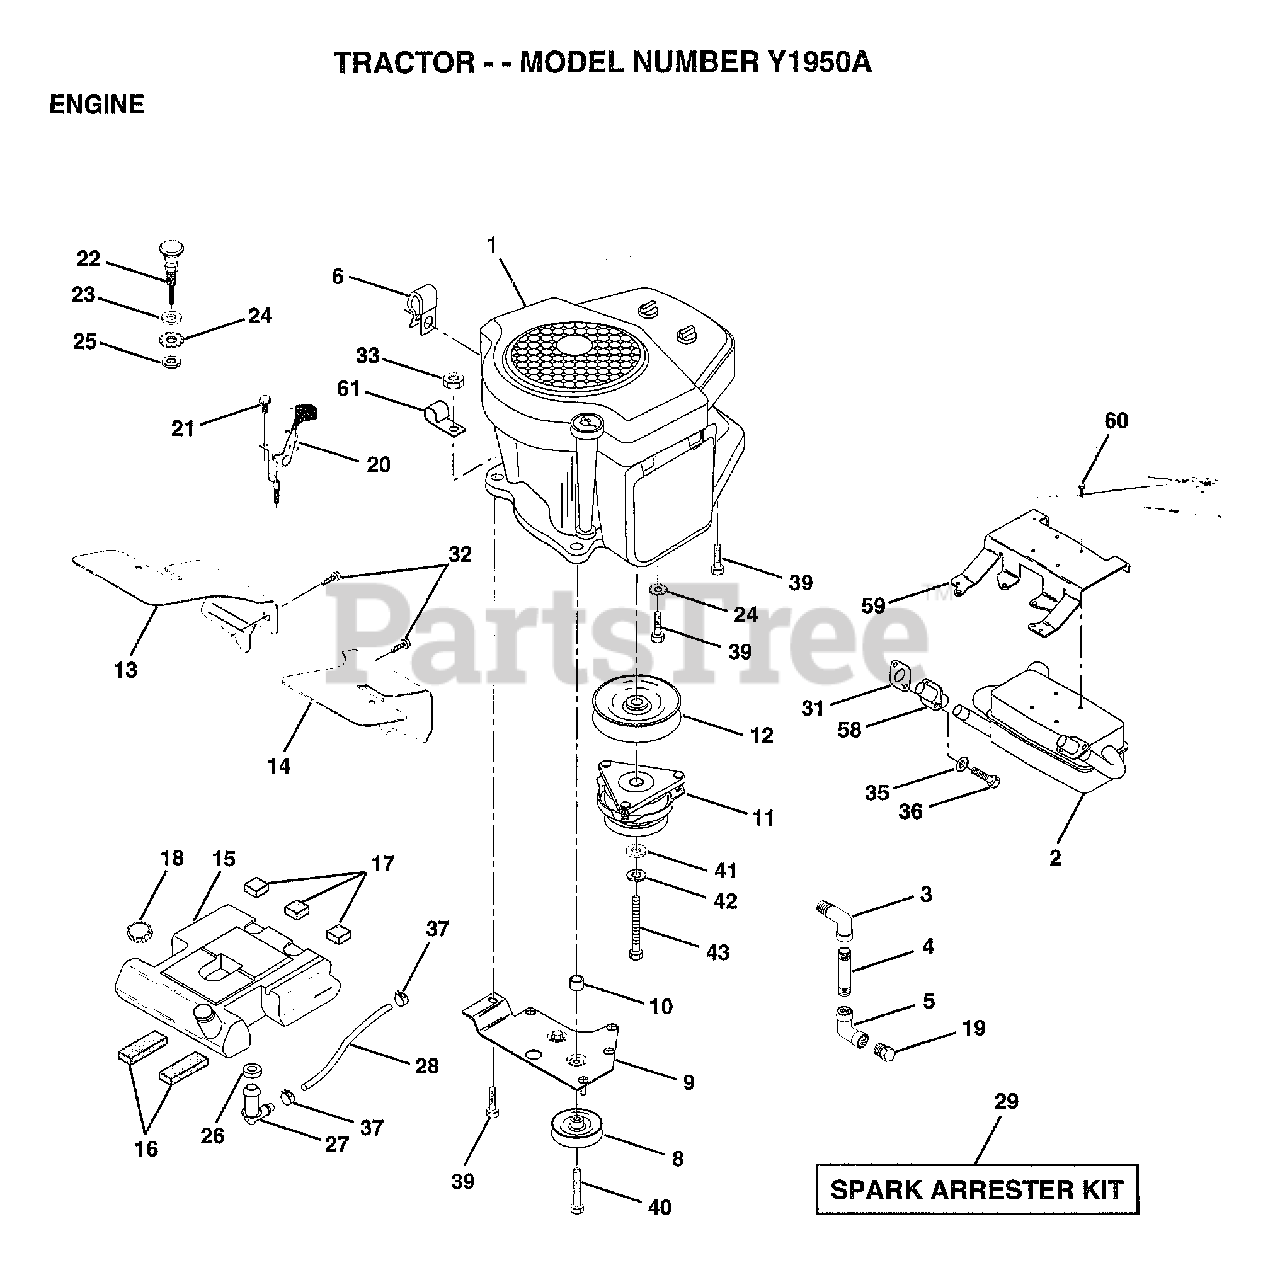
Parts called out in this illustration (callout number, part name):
2	MUFFLER.ASM.B&S
3	STREET ELBOW LT
4	PIPE NIPPLE
5	ELBOW
6	CLAMP.TUBE.DBL.EN
10	BUSHING.
12	PULLEY.ENGINE.VGT
13	BAFFLE.AIR.LH.K
16	PAD IDLER TI
17	PAD-SPACER LT
18	CAP ASM FUEL
19	PLUG T
20	CONTROL THTL 37
21	SCREW LT
22	"CONTROL.CHOKE.51"""
23	WASHER
24	LOCKWASHER
26	BUSHING OUTLET T
29	SPARK ARREST KIT
32	SCREW LT
33	NUT
35	LOCKWASHER
36	SCREW
37	HOSE CLAMP
38	LOCKWASHER
39	SCREW LT
40	SCREW.3/8-16X3.25
41	WASHER
42	LOCKWASHER
45	NUT
58	LINER.PORT.EXHAUS
59	BRACKET.MUFFLER
60	SCREW ST
61	CLIP T
